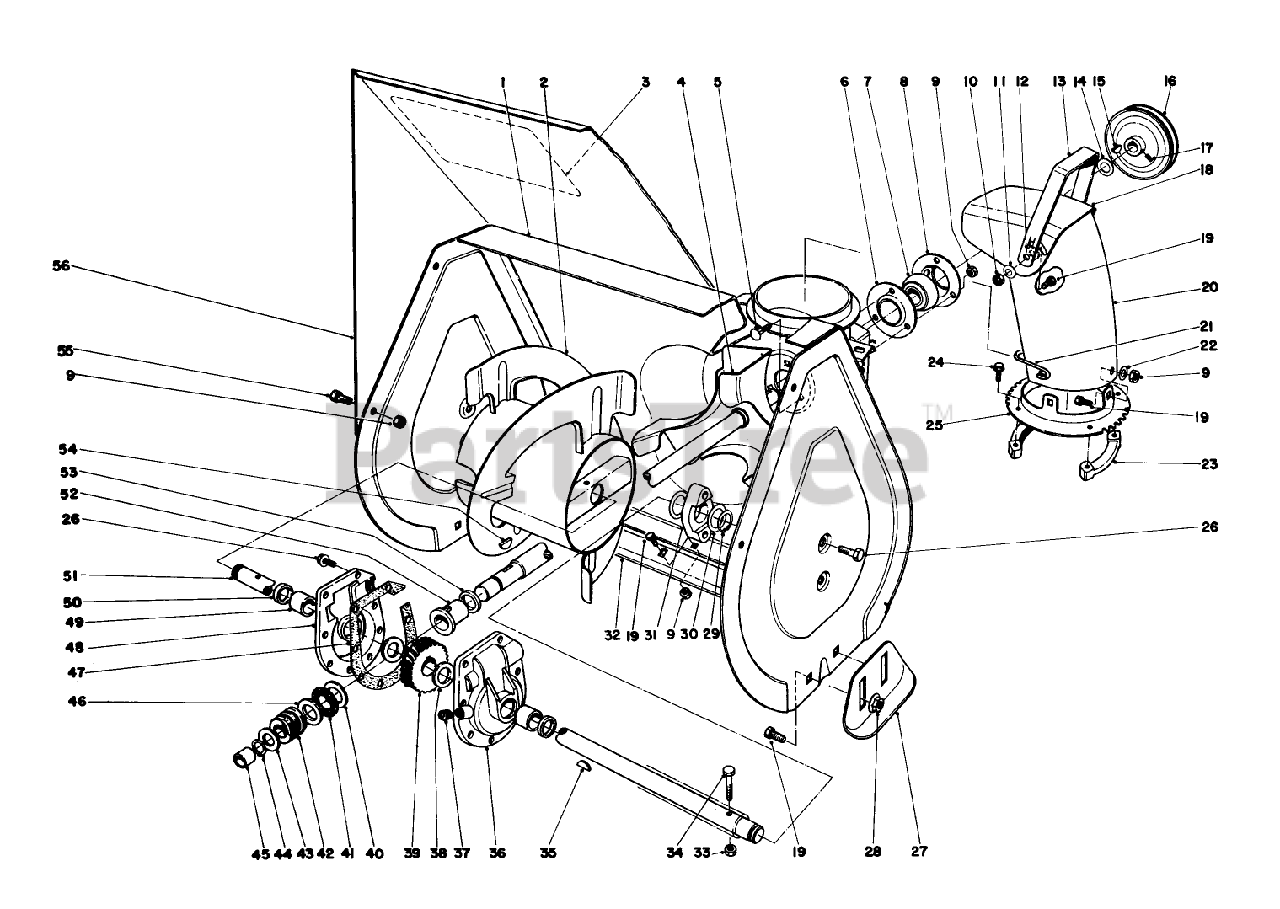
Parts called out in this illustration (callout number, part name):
5	BOLT-CARR
6	FLANGE-CUP, BEARING
8	FLANGE-CUP, BEARING
9	NUT-LOCK, NI
10	NUT-LOCK, CONE
11	WASHER-BELLEVILLE
12	Rubber Washer
14	WASHER
15	KEY-WOODRUFF
16	PULLEY
17	Set Screw
19	Screw
22	WASHER-PLAIN
23	RING-CHUTE, RETAINER
24	SCREW-SPECIAL
26	SCREW-THD ROLL, HWH
28	NUT-HF
29	RING-RETAINING
30	WASHER
34	SCREW-HH
35	KEY-WOODRUFF
37	PLUG-PIPE, SQH
38	WASHER-THRUST
40	WASHER-THRUST
41	BEARING-THRUST
43	WASHER-THRUST
44	RING-SNAP
45	BUSHING
46	WASHER-THRUST
49	BUSHING
50	SEAL-OIL
51	AUGER SHAFT
52	BUSHING-INPUT
53	RING-QUAD
54	KEY-WOODRUFF
55	SCREW-HH
